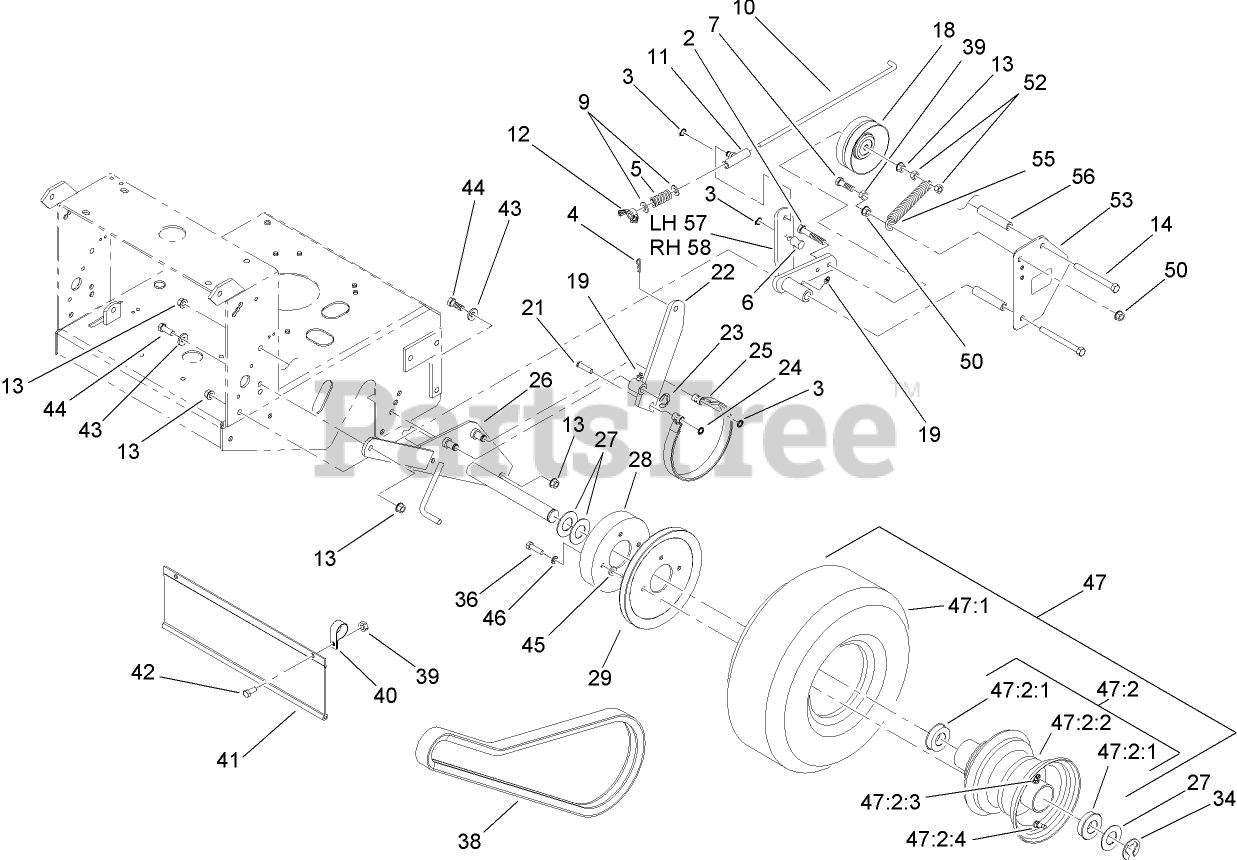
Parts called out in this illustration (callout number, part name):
2	SCREW-HH
3	RING-RETAINING
4	PIN-COTTER
5	SPRING-COMPRESSION
6	Swivel-Lever, Drive
7	SCREW-HH
9	WASHER-PLAIN
10	Linkage-Brake
11	SWIVEL-BRAKE
12	WINGNUT-NYLOCK
13	NUT-HHF, WHIZ
14	SCREW-HH
18	IDLER-WHEEL, DRIVE
19	FITTING-GREASE
21	PIN-CLEVIS
22	ARM-BRAKE
23	RING-RETAINING, EXTERNAL
24	NUT-PUSH
25	BAND-BRAKE
27	WASHER-SPACER
28	DRUM-BRAKE
29	SHEAVE-WHEEL, DRIVE
34	RING-SNAP
36	SCREW-HH
38	BELT-DRIVE, WHEEL
39	NUT-LOCK, NI
40	CLAMP-R
41	SHIELD-TRAILING
42	SCREW-HH
43	WASHER-BELLEVILLE
44	SCREW-HH
45	WASHER
46	WASHER-LOCK
47	Wheel AND Tire ASM
47:1	TIRE
47:2	WHEEL AND HUB ASM
47:2:1	BEARING-FLANGED
47:2:2	Rim ASM
47:2:3	Fitting-Grease
47:2:4	Valve Stem and Cap
50	NUT-HF
52	NUT-LOCK, NI
53	Shield-Wheel, Drive
55	SPRING-EXTENSION
56	SPACER-SHIELD
57	Arm-Idler, LH
58	Arm-Idler, RH
